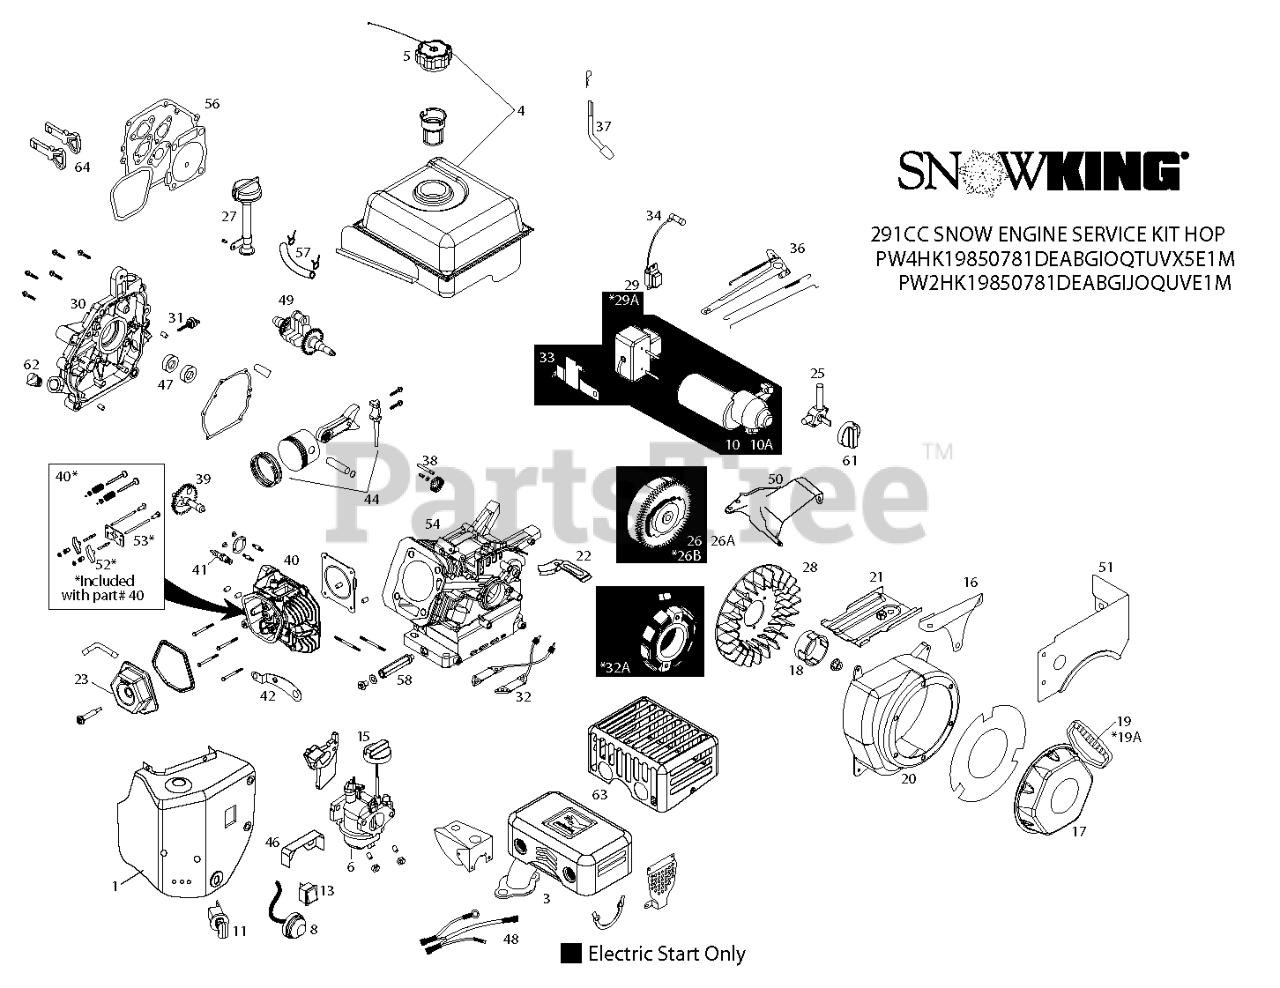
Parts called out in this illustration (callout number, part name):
1	HEATER.BOX.ASSY.SNOW(SKSN2100)
3	MUFFLER.ASSY.SNOW(SKSN4200)
4	FUEL TANK ASSY - SNOW (291CC)
5	FUEL.TANK.CAP.SNOW(SKSN4301)
6	CARBURETOR.ASSY.SNOW(SKSN2302)
8	PRIMER.BULB.ASSY(SKSN4304)
10	ELECTRIC.START.ASSY(SKSN2400.2
10A	STARTER, ELECTRIC, 230V
11	KEY.SWITCH.ASSY.SNOW(SKSN4401)
13	ON/OFF.SWITCH.SNOW(SKSN4403)
15	CHOKE.KNOW.SNOW(SKSN4500)
16	GOVERNOR.LINK.SHIELD(SKSN2501)
17	RECOIL.START.ASSY.(SKSN2600)
18	STARTER.CUP.SMALLSNOW(SKSN2601
19	STARTER.GRIP.SNOW(SKSN2603.1)
19A	HANDLE.RECOIL.DELUXE.LCT
20	HOUSING.BLOWER.ASM
21	SHIELD.CYLINDER.SNOW(SK4141010
22	SHIELD.U/FYWHL.CHARG(SKSN4604)
23	VALVE.COVER.LCT.414CC.
25	FUEL.PETCOCK.SNOW(SKSN4900)
26	FLYWHL.ASSY.ELECT.(SK2911701)
26A	FLYWHL.ASSY.MANUL.(SK2911700)
26B	FLYWHEEL.EL.ST.SKSNO2401.1
27	HIGHOIL.FILL.ASSY.KIT(SKSN4911
28	FLYWHEEL.FAN
29	IGNITION.COIL.(CDI).291-414CC
29A	COIL.IGN.CDI.SKSN2403.1
30	CRANKCASE.COVER.ASY(SK2913600)
31	DIPSTK.OIL.BLK.LCTSK4143711.1
32	CHARGING.COIL.AC/DC(SK4141710)
32A	ALTERN.60WATT.SKSN2402.1
33	ELECTRIC.START.BRKT(SKSN4405)
34	SPARK.PLUG.BOOT.SNW,SKSN4691.1
36	GOVERNOR.ARM.ASSY.(SKSN2502)
37	GOVERNOR.SHAFT.(SK2913100)
38	GOVERNOR.GEAR.ASSY(SK2912900)
39	CAMSHAFT.LCT.291CC
40	CYLINDER.HEAD.ASSY(SK2911000)
41	SPARK.PLUG(SK2911550)
42	CDI.BOX.BRKT.SNOW(SKSN4402)
44	PISTON.AND.ROD.ASSY(SK2911400)
46	SHIELD.VAPOR(SKSN4606)
47	RP KIT.SEAL.LCT.SK2913905
48	WIRE.HARNESS(SKSN4406)
49	CRANKSHAFT.LCT.291CC.SNOW
50	TOP.SHIELD.LCT.
51	FUEL.TANK.SKIRT(SKSN2101)
52	ROCKER ARM KIT
53	PUSH ROD TAPPET KIT
54	CYLINDER.ASSEM.291CC.LCT.SNOW
56	ENGINE.GASKET.KIT(SK2914300)
57	FUEL HOSE KIT
58	EXTENDED OIL DRAIN TUBE
61	FUEL KNOB-SNOW
62	NONREMVABLE.OIL.PLUG(SK4143715
63	SHIELD.MUFFLER.
64	KEY SET(2 KEYS) SKSN0407.1
